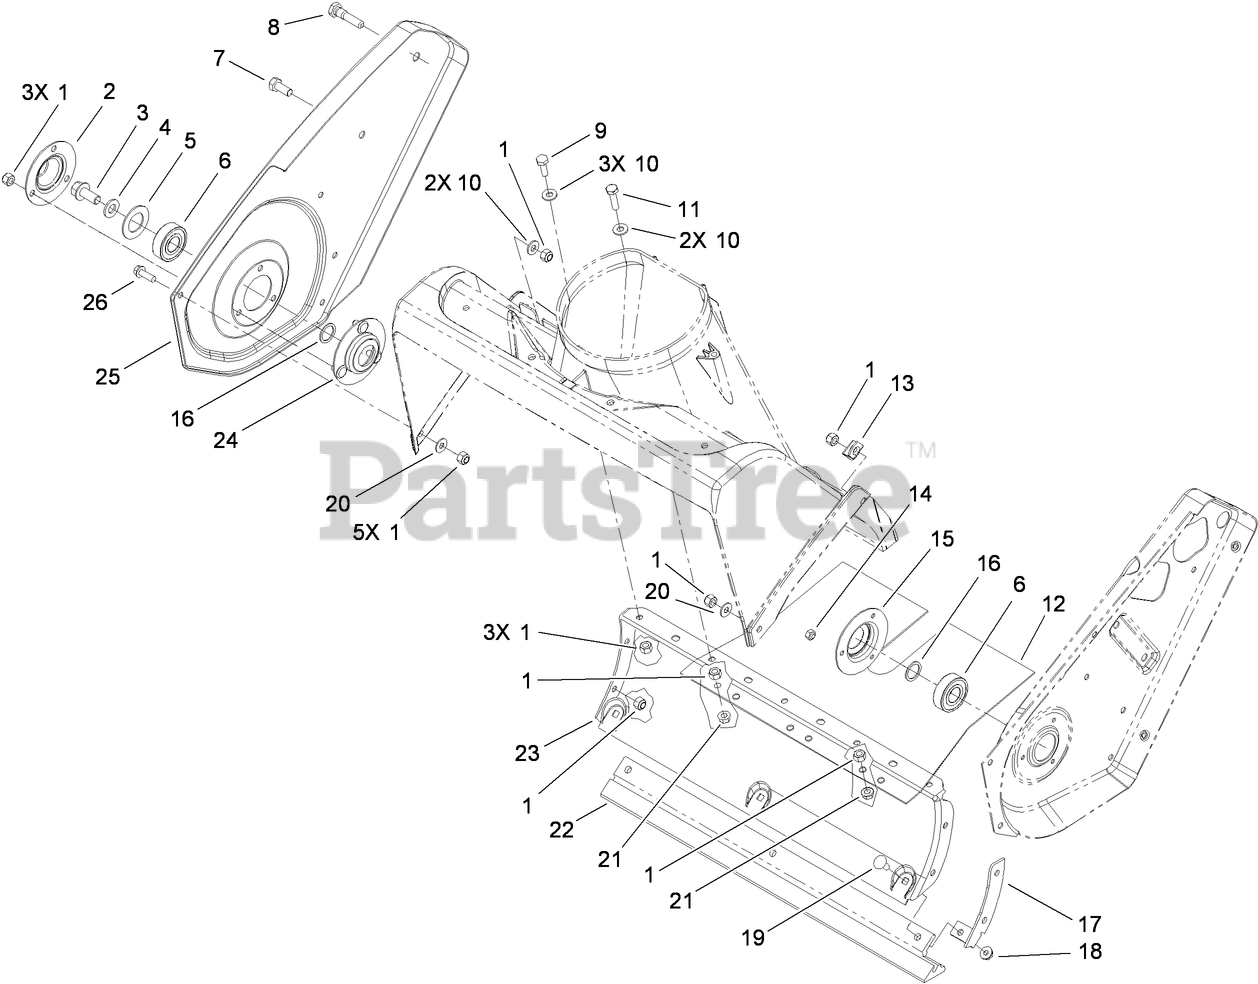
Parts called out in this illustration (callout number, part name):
1	NUT-LOCK, NI
2	RETAINER-BEARING
3	SCREW-HHF
4	WASHER-FLAT
5	WASHER-RUBBER
7	SCREW-HH
8	PIN-ROTOR
9	SCREW-HH
10	WASHER-FLAT
11	SCREW-HH
12	COVER-BOTTOM
13	BRACKET-HOUSING
14	NUT-LOCK, NI
15	FLANGE-BEARING
16	WASHER-THRUST
17	BRACKET-HOUSING, LOWER
18	NUT-KEPS
19	SCREW-CARR
20	WASHER-FLAT
21	NUT-LOCK, HHF
22	SCRAPER
24	FLANGE-BEARING
25	SIDEPLATE-RIGHT
26	SCREW-HWH
